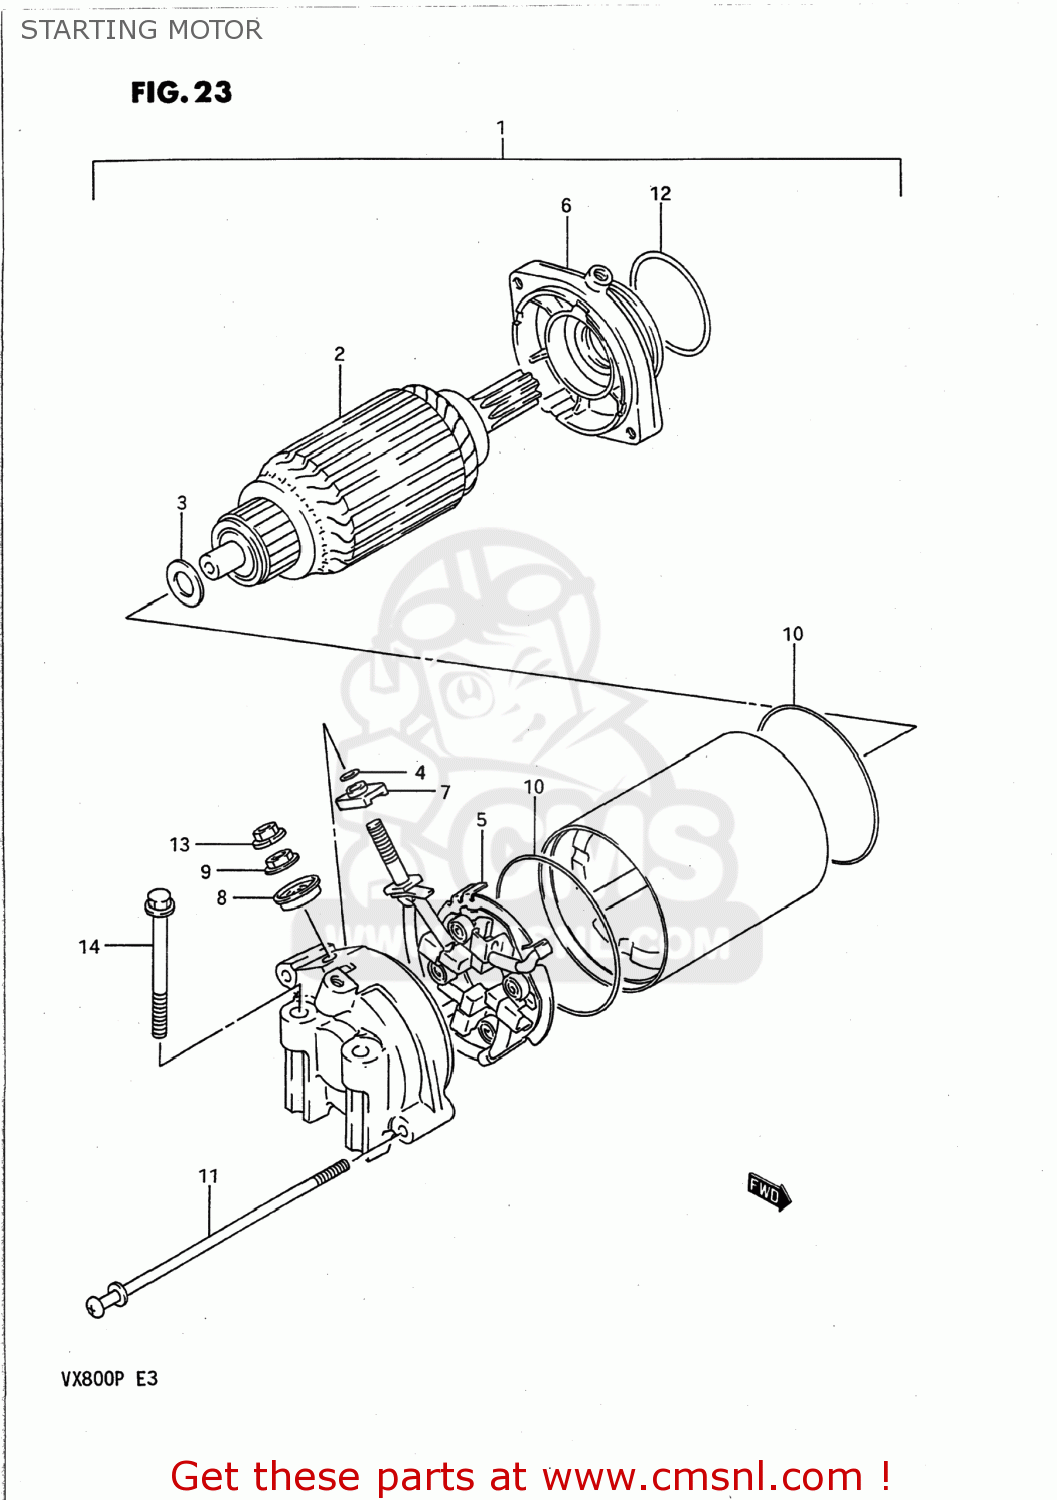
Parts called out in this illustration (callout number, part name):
1	MOTOR ASSEMBLY,STARTING
2	ARMATURE
3	SHIM,ARMATURE
4	O RING
5	HOLDER SET,BRUSH
6	BRACKET SET
7	BUSHING
8	BUSHING
9	NUT
10	O RING
11	BOLT
12	O RING
13	NUT
14	BOLT
